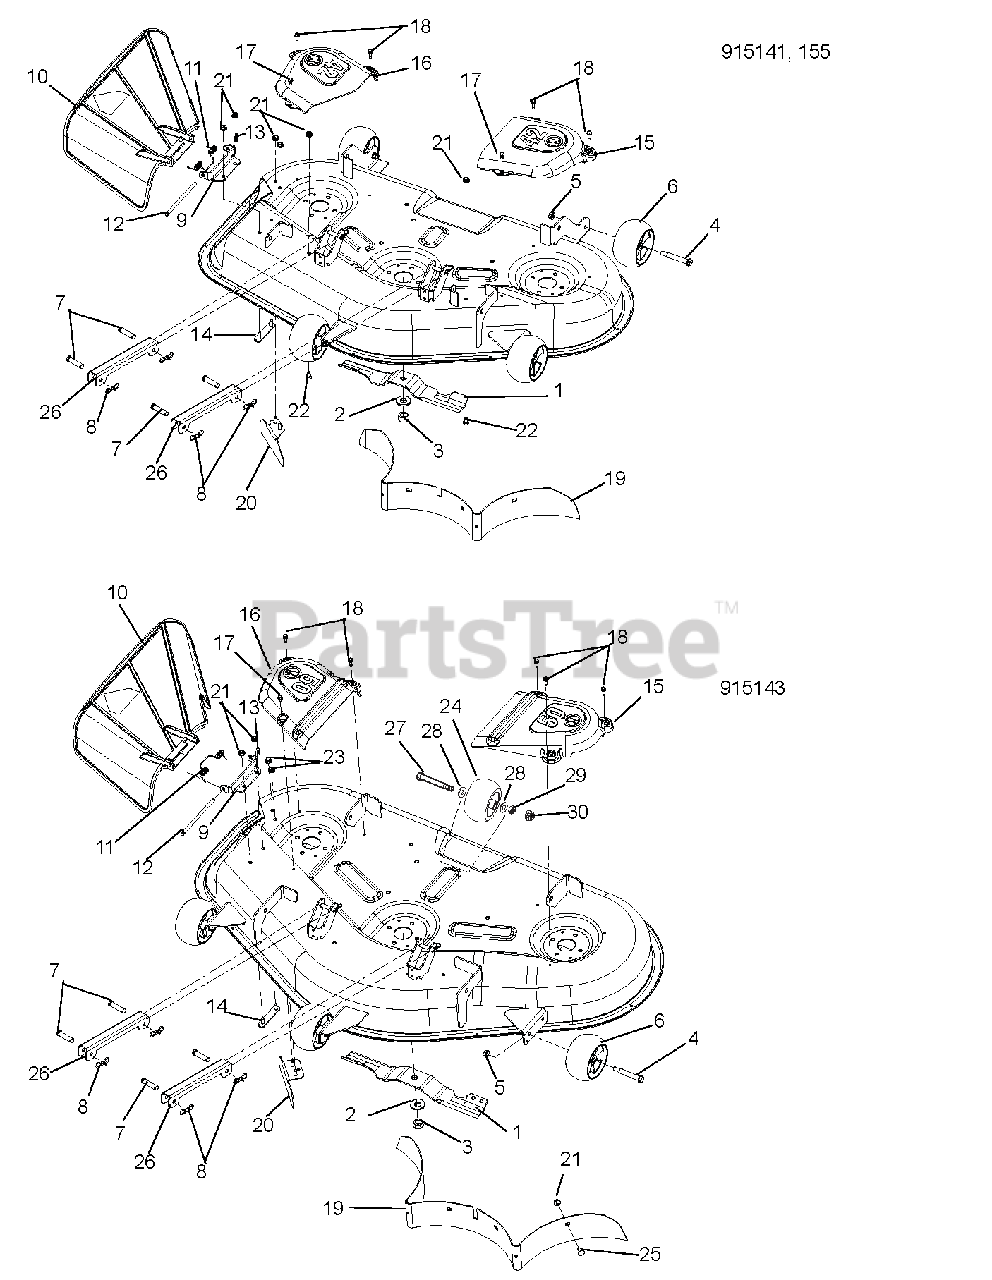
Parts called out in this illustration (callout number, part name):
1	MOWER BLADE, 14.83 LENGTH
1	BLADE, MOWER 17.35
2	WSHR-BLVL .669X1.535X.138
3	NUT-HEX .62-18 YWZC
4	BLT-SHLDR .38-16X2.50 HWH G5
5	@NUT-LK-TOP-FLG .38-16 YWZC
6	ANTI-SCALP WHEEL - 5X OS
7	PIN-CLEV .375 X 2.00 YWZC
8	PIN, BOW TIE LOCKING
9	BRKT-DISCHARGE CHUTE MOUNT 42"
9	BRKT, CHUTE MOUNT
10	DISCHARGE CHUTE
11	SPRING-TORSION
12	PIN, 5/16 X 5.80"
13	PIN-HAIR INT .08X.18X1.18 YWZC
14	WMT-DISCHARGE CHUTE MT. STRAP
15	BELT COVER - LH 42"
15	BELT COVER - LH 50"
16	BELT COVER - RH 42"
16	BELT COVER - RH 50"
17	SCR-TAP .25-20X.50 HWH TR YWZ
18	SCR-TAP .25-20X.75 HWH TR YWZ
19	BAFFLE, REAR (42)
19	BAFFLE-50" STAMPED DECK REAR
20	WMT, DISCHARGE BAFFLE (42)
20	BAFFLE, DEFLECTOR (50)
21	@NUT-LK-TOP-FLG .31-18 YWZC
22	@BLT-HEX .31-18X.50 GR5 YWZC
23	@NUT-LK-NYL-FLG .31-18 YWZC
24	ROLLER
25	@BLT-RHDSSQNK .31-18X.75 G5YZ
26	BRKT-STABILIZER LINK
27	@BLT-HEX .38-16X3.50 GR5 YWZC
28	@WSHR-FL-STL.406X.812X.065 YWZ
29	@NUT-LK-CTR-JAM .375-16 YWZC
30	@NUT-LK-NYL-FLG .38-16 YWZC
